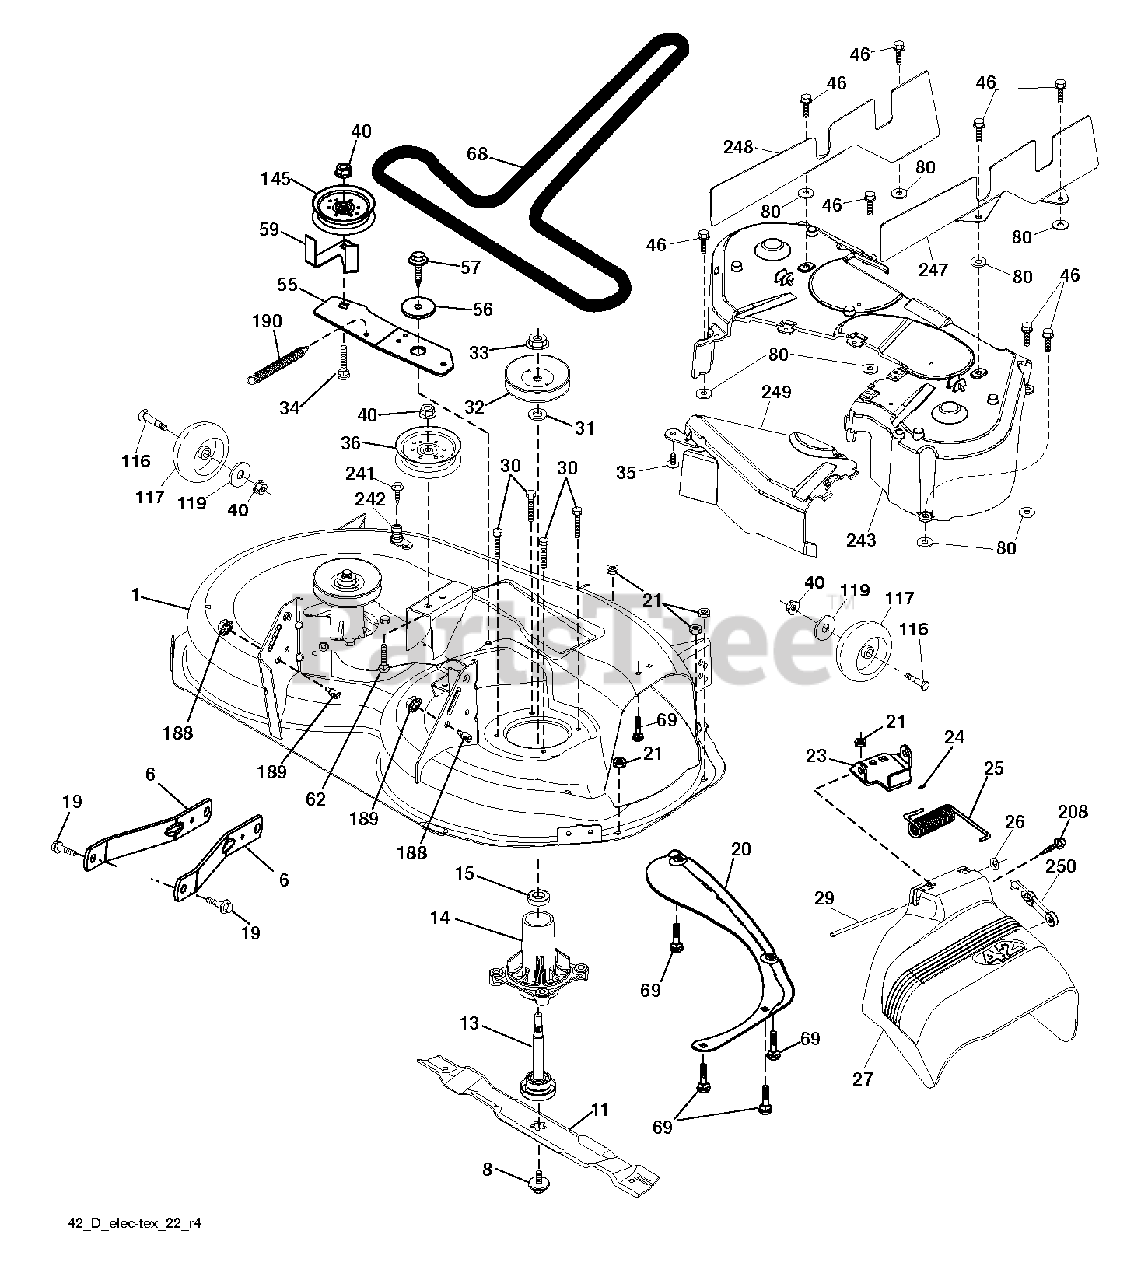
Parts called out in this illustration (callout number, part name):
6	ARM.SUSPENSION.MOWER.R
8	SCREW 7/16 X 20 X 1" HEX HEAD
11	BLADE.REVOLUTION 42"BAGGER
13	MANDREL.ASM.REV.TALL.N/GRSABLE
14	HOUSING.MANDREL.REV.TALL.N/GRS
19	BOLT.SHOULDER
20	BAFFLE.VORTEX
21	LOCKNUT
23	BRKT.DEFLECTOR.38"2005+
24	CAP-SLEEVE LT
25	SPRING.TORSION.DEFLECT
26	NUT PUSH M
27	DEFLECTOR ASM.42"TEX.FRENCH
29	ROD.HINGE
30	SCREW, WASHER HEAD
31	WASHER.SPACER.MANDREL
32	PULLEY/MANDREL
33	NUT.FLANGE.LOCK.TOP
34	BOLT.3/8-16X1.50
35	FASTENER.XMAS.TREE
36	PULLEY.IDLER.2006
40	NUT LOCK FLG 3/8-16 UNC
46	SCREW.1/4-20X5/8
55	IDLER.ARM.42"
56	SPACER.RETAINER
57	SCREW 3/8-16X1
59	GUARD, BELT
68	BELT V SECONDARY
69	BOLT
80	PALNUT 1/4
116	BOLT M
117	WHEEL.GAGE.HALF.SPOKED
119	WASHER
145	PULLEY.IDLER.48"PRIMARY
188	STUD.FASTNER.W/ANTI-ROTATE
189	NUT LOCK HEX FLANGE 5/16-18
190	SPRING.MOWER.DRIVE.ELECTRIC
208	SCREW 3/8-16X1/2
241	SCREW.TT.#10-32X.5.3/8.FLANGE
242	PORT.WASHOUT
243	COVER DECK
247	SHIELD DECK RIGHT
248	SHIELD DECK LEFT
249	COVER CABLE CLUTCH
250	ELASTIC STRAP KIT
